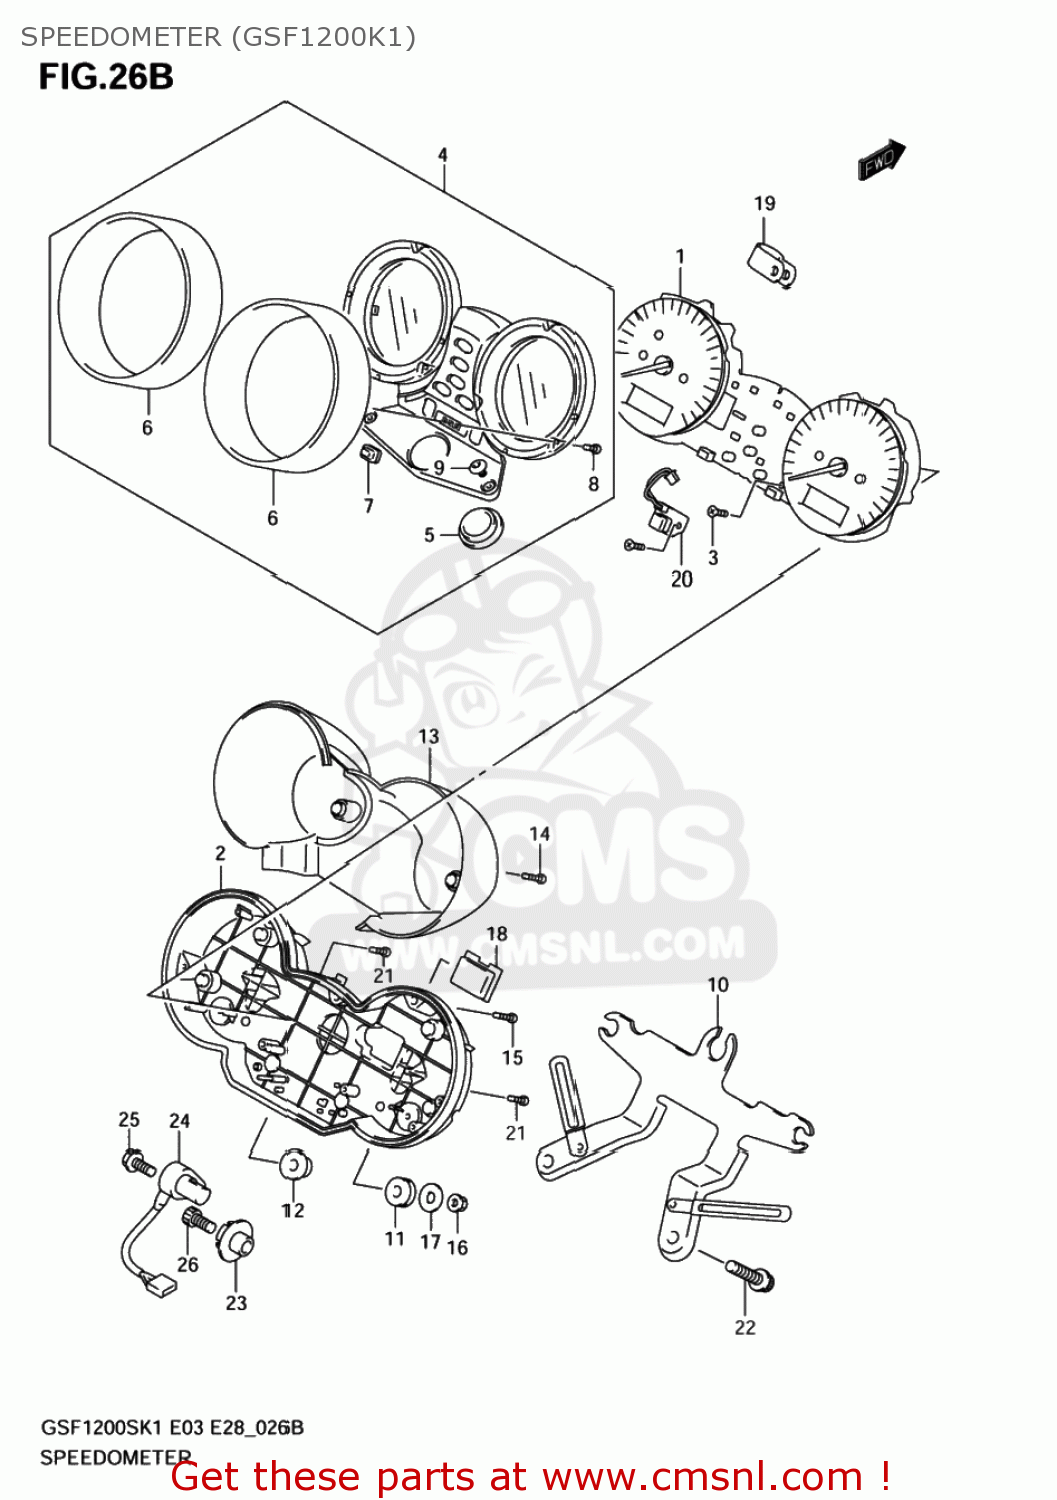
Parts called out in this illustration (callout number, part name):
1	SPEEDOMETER
2	CASE ASSY,LWR
3	SCREW(4X14)
4	UPR CASE ASSY
5	DAMPER
6	RING
7	RUBBER,SWITCH
8	SCREW(2.3X8)
9	TAPPING CAP(5X10.2)
10	BRACKET
11	CUSHION
12	CUSHION
13	COVER
14	SCREW,PAN HEAD(3X14)
15	SCREW(3X16)
16	NUT
17	WASHER(5.2X16X1)
18	GROMMET
19	CLAMP
20	SWITCH,PRINT CIRCUIT
21	SCREW,PAN HEAD(3X16)
22	BOLT MAGNETO S
23	ROTOR,SPEED
24	SENSOR,SPEED
25	BOLT
26	BOLT
